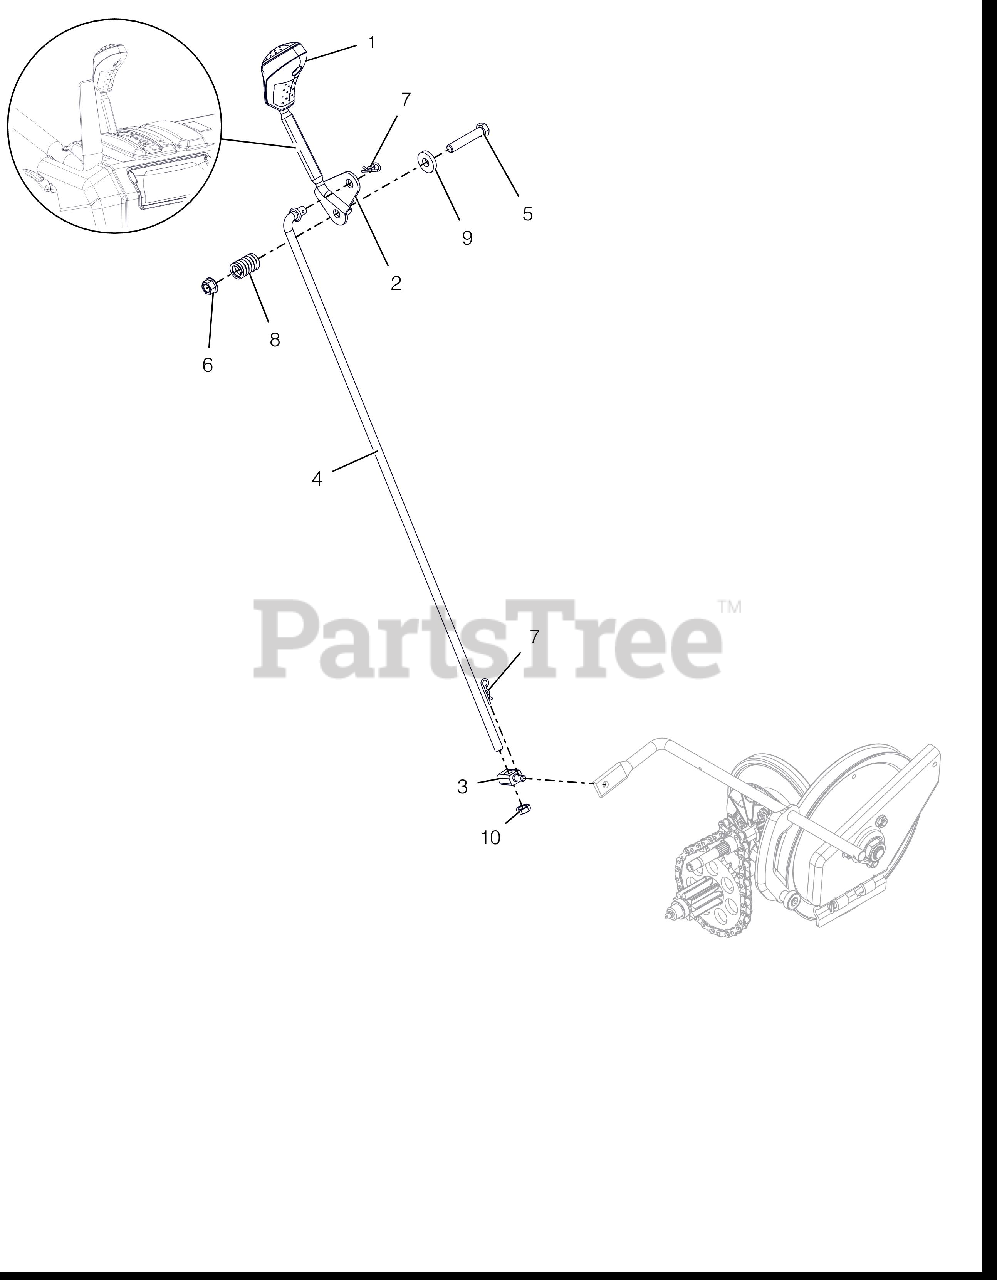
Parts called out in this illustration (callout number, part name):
1	KNOB, CONTROL, DASH
2	WELDMENT,LG DASH SPEED CONTROL
3	PIVOT,SHIFT ROD .375-16(TRUNN)
4	ROD, SHIFT-PRO
5	@BLT-HEX .38-16X2.00 GR5 YWZC
6	@NUT-LK-TOP-FLG .38-16 YWZC
7	PIN-HAIR INT .08X.18X1.18 YWZC
8	SG-COMP .125X.781X1.250
9	WSHR-FL-STL .406X1.00X.188 YWZ
10	NUT-HEX-JAM .375-16 YWZC
